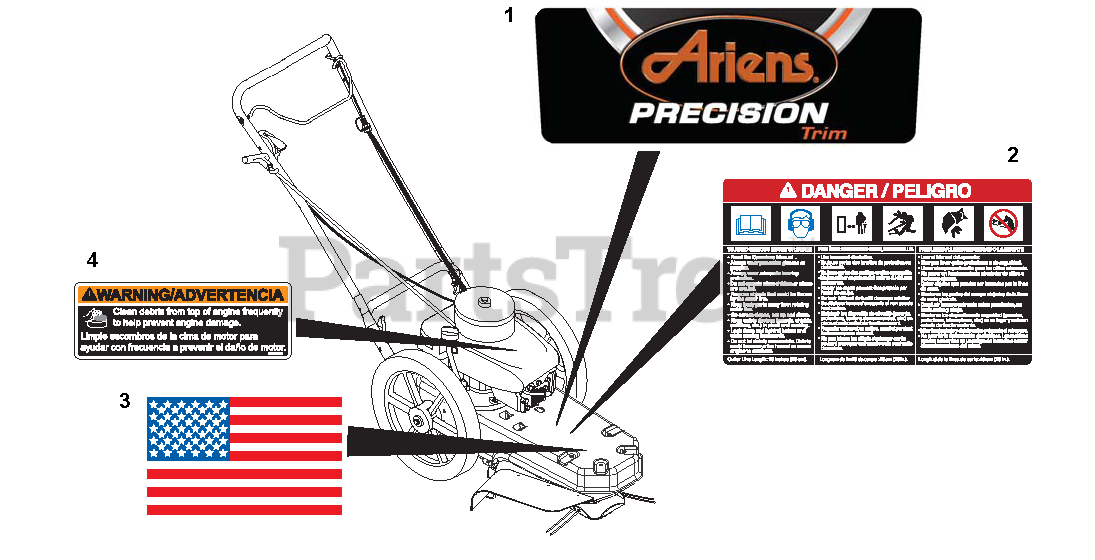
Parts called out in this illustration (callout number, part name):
1	DECAL, ARIENS PRECISION TRIM
2	DECAL - DANGER-STRING TRIMMER
3	DECAL, AMERICAN FLAG
4	DECAL, TRIMMER DEBRIS WARNING
